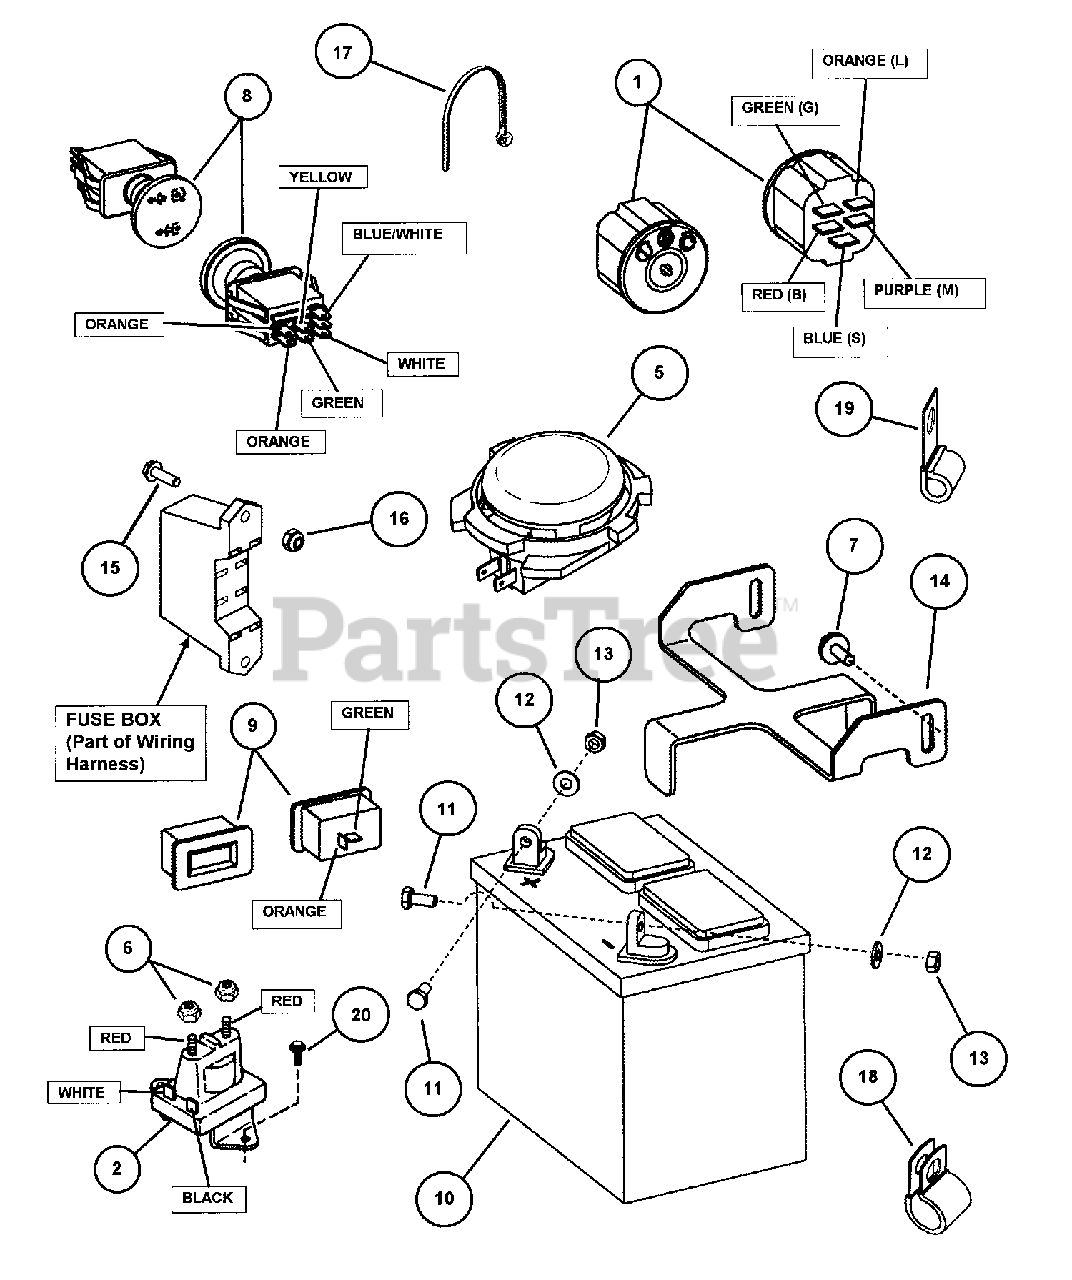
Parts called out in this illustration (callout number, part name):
1	SWITCH, Ignition
2	SOLENOID, Super Trombetta
5	SWITCH, Seat, NC
6	NUT, 1/4-20 HEX NYLON LOCK
7	SCREW, 1/4-20 x 5/8" Hex Head w/loose captured washer
8	SWITCH, PTO, Yellow
9	HOUR METER w/2 Flash Alerts
10	BATTERY, 12V. 11 Plate 375CCA
11	SCREW, 1/4-20 x 5/8" Hex Head Cap GR5
12	WASHER, 9/32 I.D. x 5/8" O.D. Flat
13	NUT, 1/4-20 Hex Center Lock GR5 or B
14	BRACKET, Battery Hold-Down
15	SCREW, #10-32 x 5/8" Hex Washer Self-Tap
16	NUT, #10-32 Hex Nyloc
17	CABLE TIE, 7" long
18	CLIP, Harness
19	CLIP, Open J 3/8" Cushioned
20	SCREW, 1/4-20 x 1/2" Hex Washer Self-Tap
